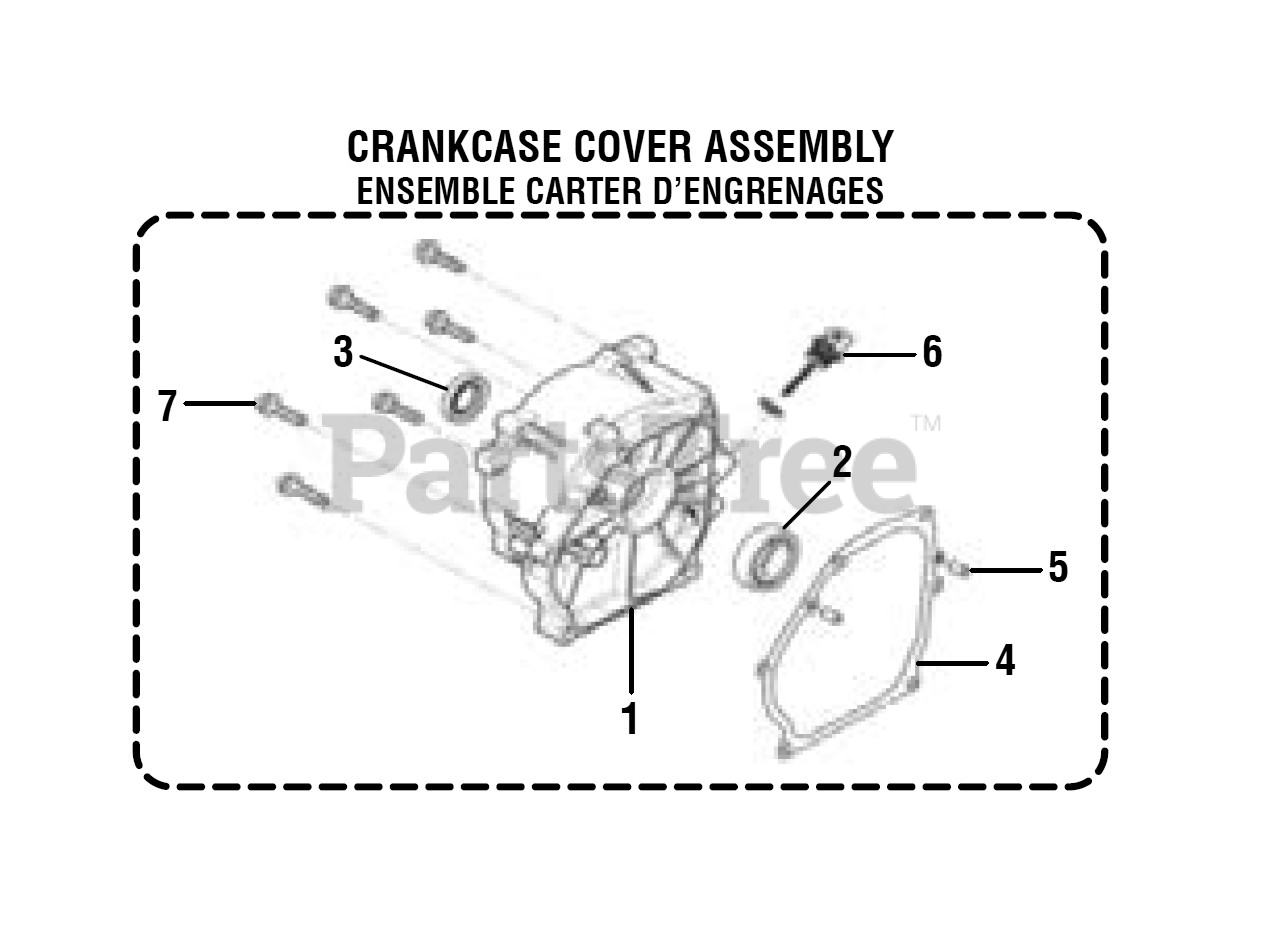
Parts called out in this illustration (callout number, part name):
1	Crankcase Cover
2	Ball Bearing
3	Oil Seal
4	Crankcase Gasket
6	Oil Dipstick Assembly
